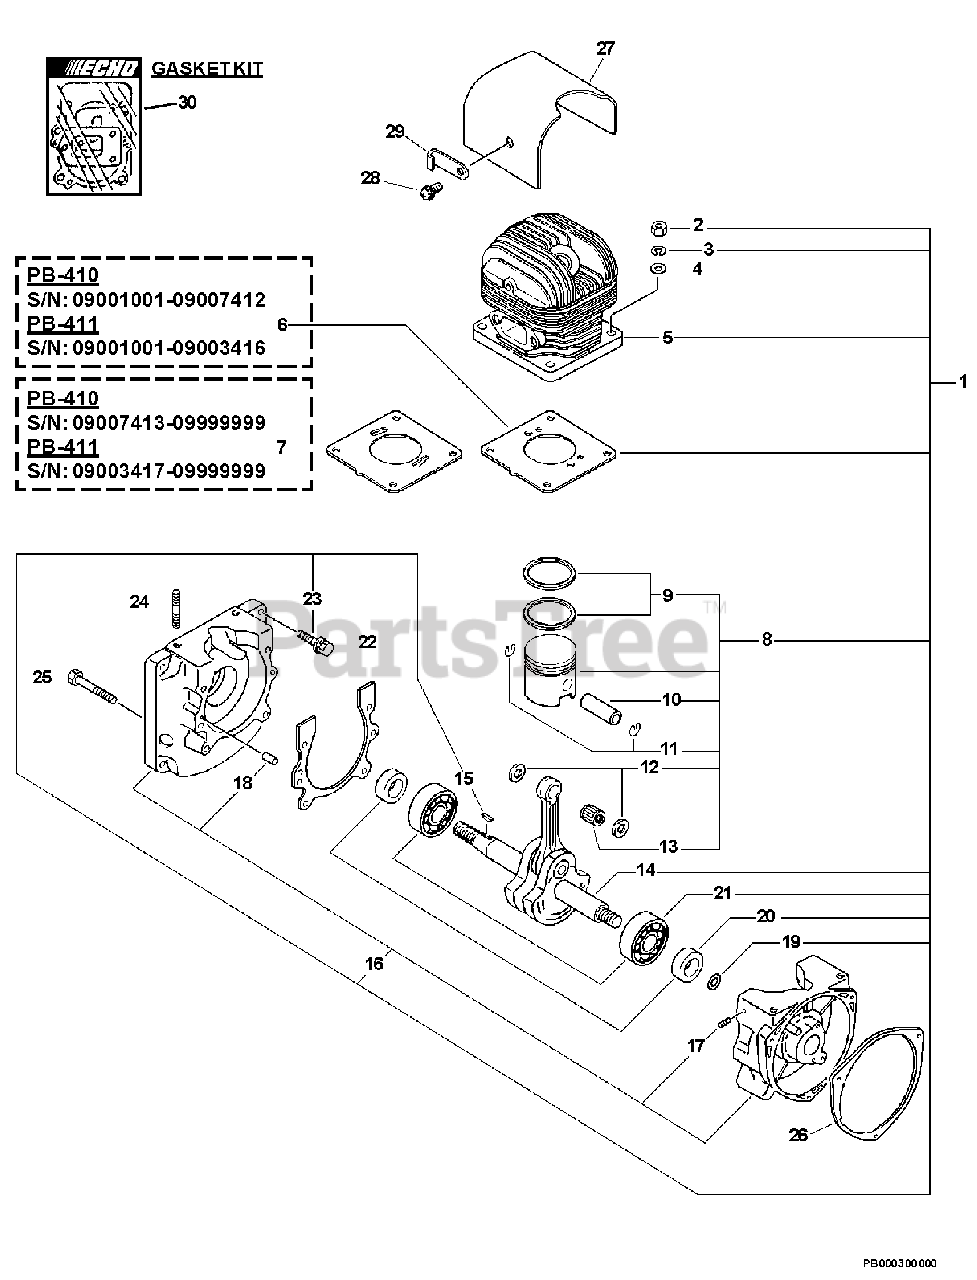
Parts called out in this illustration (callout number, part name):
1	SHORT BLOCK
2	NUT, HEX M6
3	WASHER, SPRING 6
4	WASHER 6.5×11.5×0.8
5	CYLINDER
6	GASKET, CYLINDER
7	GASKET, CYLINDER
8	PISTON KIT
9	RING, PISTON
10	PIN, PISTON
11	RING, SNAP 8
12	WASHER, THRUST
13	BEARING, NEEDLE 10
14	CRANKSHAFT ASSY
16	CRANKCASE KIT
17	CONNECTOR
18	PIN, LOCATING 5×10
19	WASHER PB-400
20	SEAL, OIL
21	BEARING, BALL
22	GASKET
26	GASKET, STARTER
27	COVER, CYLINDER
28	BOLT 6×10
29	CLIP, CORD
30	GASKET KIT
